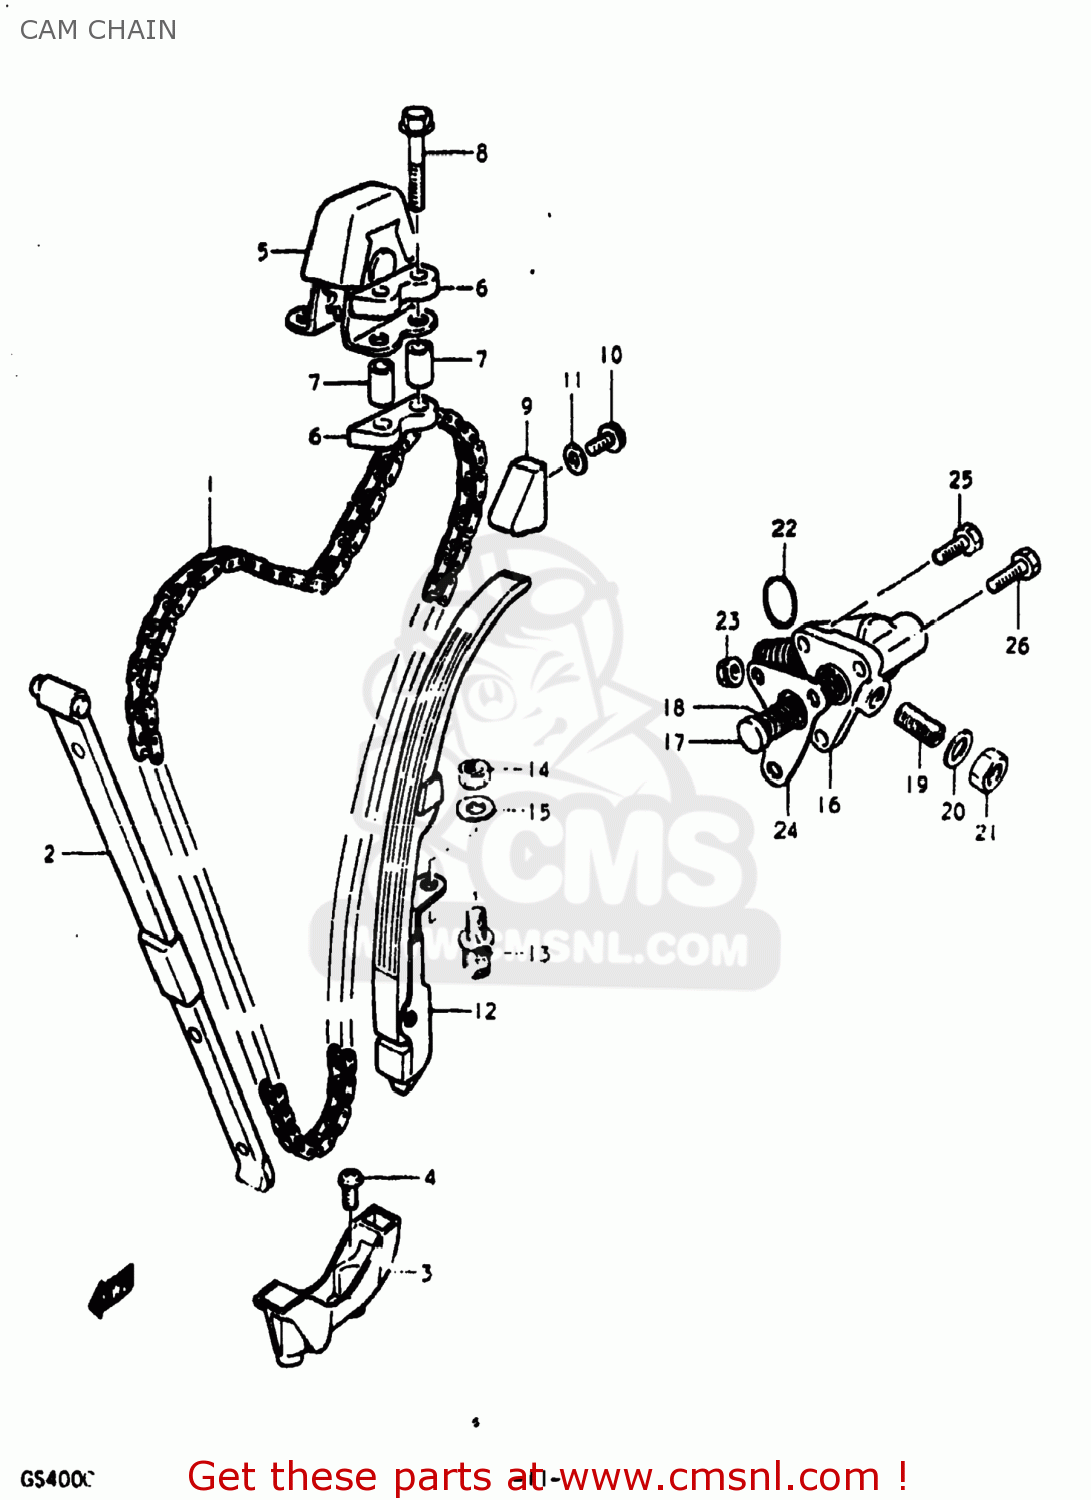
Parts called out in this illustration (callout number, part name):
1	CHAIN,CAMSHAFT DRIVE(120L)
2	GUIDE,CAM CHAIN
3	HOLDER,CAM CHAIN GUIDE
4	SCREW
5	IDLER,CAM CHAIN
6	CUSHION,IDLER
7	SPACER
8	BOLT
9	GUIDE,CAM CHAIN
10	BOLT
11	GASKET (NAS)
12	TENSIONER,CAM CHAIN
13	STUD
14	NUT 8MM
15	WASHER
16	ADJUSTER ASSEMBLY,TENSIONER
17	ROD,PUSH
18	SPRING
19	SCREW
20	WASHER
21	NUT
22	O-RING
23	NUT
24	GASKET,TENSIONER ADJUSTER (MCA)
25	SCREW
26	SCREW
